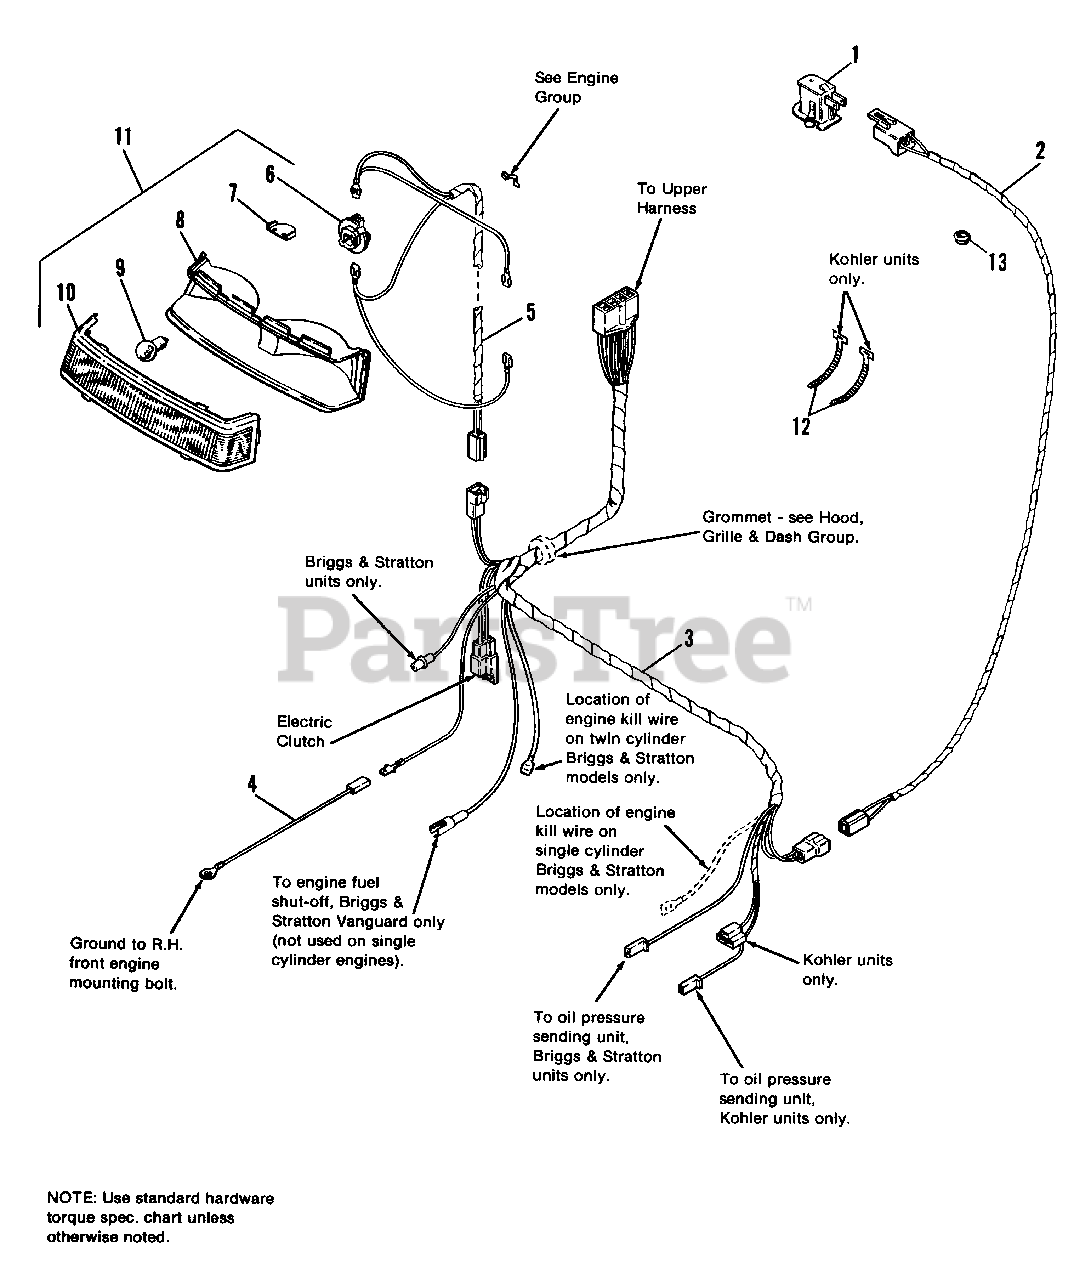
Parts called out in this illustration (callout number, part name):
1	SWITCH, Seat, Operator Present
2	WIRE ASSY., Seat Switch
3	HARNESS ASSY., Lower (16 HP Hydro Units)
3	HARNESS ASSY., Lower (12.5 HP Hydro Units)
3	HARNESS ASSY., Lower (12.5 HP Gear Units)
4	WIRE ASSY., Engine Ground
5	WIRE ASSY., Headlight
6	SOCKET, Bulb
7	HEAT SHIELD
8	BEZEL, Headlight
9	BULB, Headlight, 12.8V
10	LENS, Headlight
11	HEADLIGHT ASSY. (Incl. Ref. Nos. 6-10)
12	TlE, Cable (Gear Unit Only)
13	BUSHING, Snap (Qty. 2 on 12.5 HP Hydro, Qty. 1 on 12.5 HP Gear)
